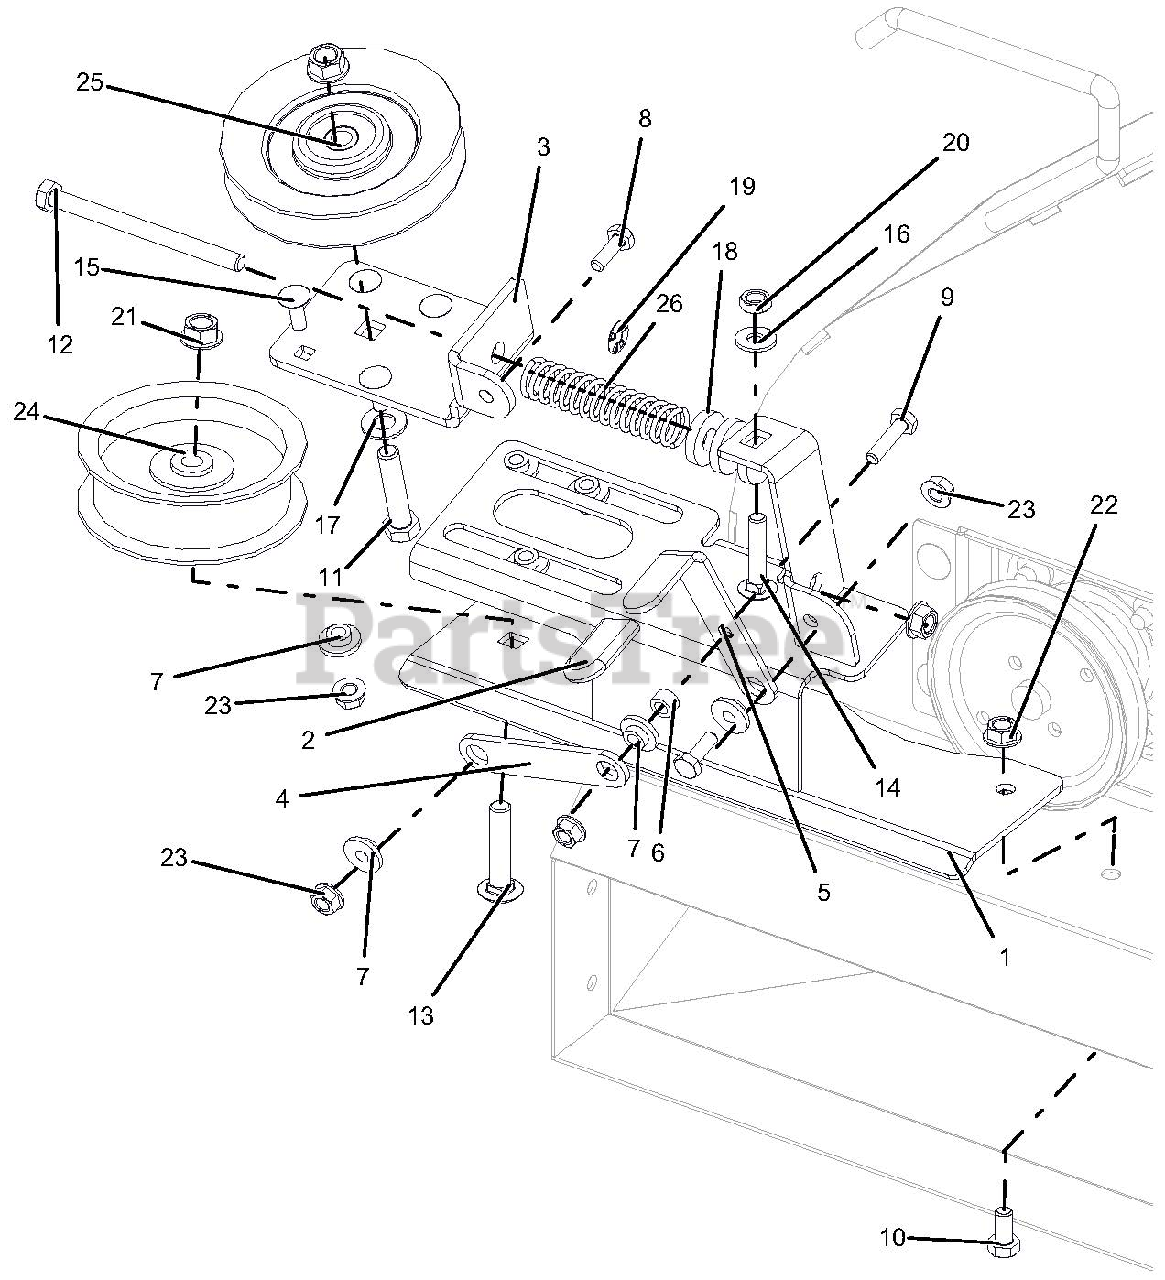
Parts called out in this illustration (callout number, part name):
1	WLDMT, IDLER MOUNT
2	GRIP, SEAT LEVER, GREY
3	BRKT, ADJ PULLEY IDLER
4	LINK, TENSIONER
5	HANDLE, TENSIONER
6	BSHG-SLV .261X.44X.25
7	BSHG, FLANGE .265X.437X.250X.750
8	BLT-HEX .25-20X.75 GR5 YWZC
9	BLT-HEX .25-20X1.00 GR5 YWZC
10	BLT-HEX .31-18X.625 GR5 YWZC
11	BLT-HEX .38-16X1.75 GR5 YWZC
12	BLT-HEX .31-18X4.00 GR5 YWZC
13	BLT-RHDSSQNK .38-16X1.75 G5YZ
14	BLT-RDHDSQNK .31-18X1.50 G5 YWZC
15	BLT-RDHDSQNK .25-20X.75 G5 YWZC
16	WSHR-FL-STL.312X.734X.065 YWZ
17	WSHR-FL-STL.406X.812X.065 YWZ
18	WSHR-FL-STL .406X1.00X.188 YWZC
19	NUT, PUSH .312
20	NUT, JAM .312-18 YWZC
21	NUT, LK-TOP-FLG .38-16 YWZC
22	NUT, LK-TOP-FLG .312-18 YWZC
23	NUT, LK-TOP-FLG .25-20 YWZC
24	IDLER, FLANGE .38ID X 3.50
25	IDLER, V, 4.00X.38
26	SPRG, COMPRESSION
